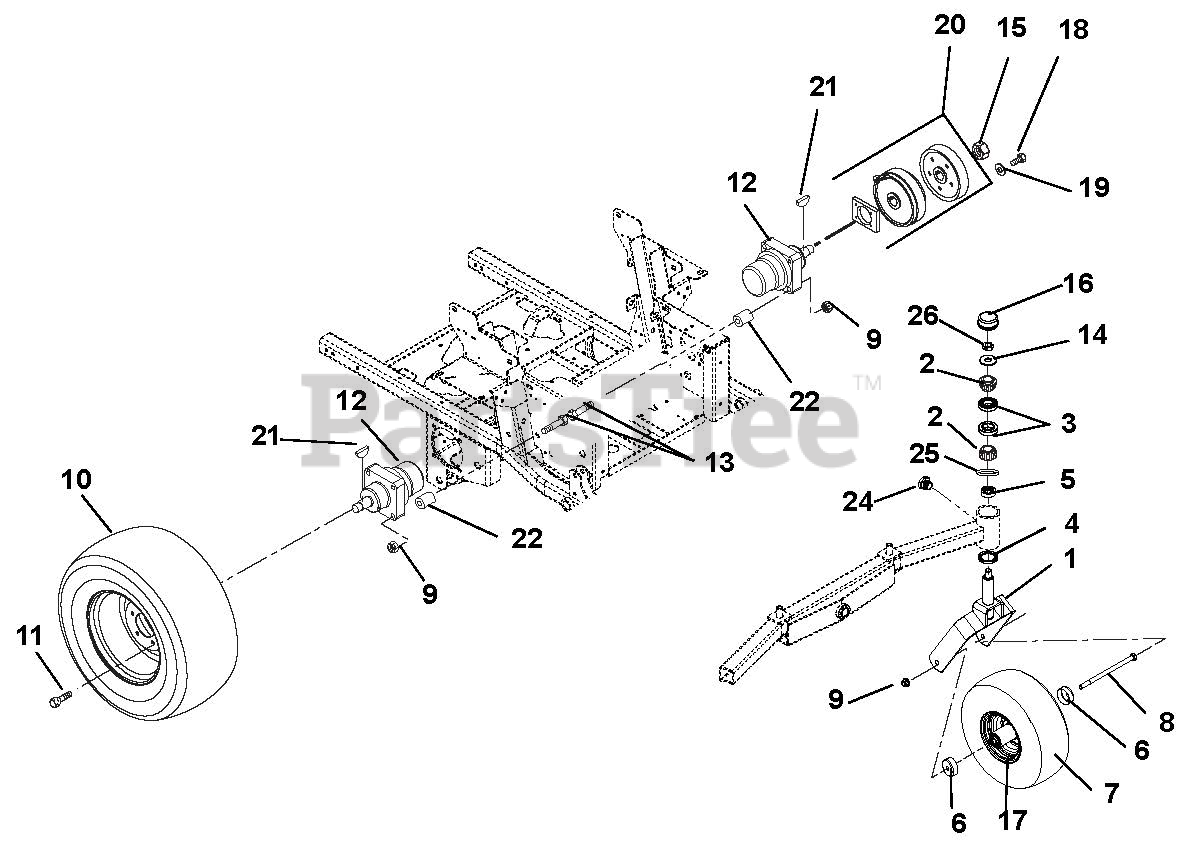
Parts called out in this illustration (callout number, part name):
1	Fork, Front
2	Bearing, Cone
3	Bearing, Cup 2.328 x .465
4	Bearing Seal 1.75 x 2.332 x .312
5	Spacer, Front Caster Fork
6	Shield, Wheel Bearing
7	Wheel/Tire Assembly, 15 x 6-6, Smooth
7	Tire, 15 x 6-6, Smooth
8	Bolt, Hex .50-13 x 9.00 Grade 5
9	Nut, Locking Top Flange .50-13
10	Tire/Wheel Assembly, 24 x 12.00-12
10	Tire, 24 x 11.50-12
11	Bolt, Lug .50-20 x 1.38
12	Wheel Motor, Parker
13	Bolt, Wheel Motor .50-13 x 5.00
14	Washer, Flat Steel .812 x 2.00 x .148
15	Nut, Top Lock Jam .75-16
16	Cap, Dust
17	Bearing, Cup 1.78 x .475
17	Bearing, Cone .750 x .61
18	Bolt, Hex .31-18 x 1.50 Grade 8 EP30
19	Waher, Lock .31 x .078
20	Kit, Parking Brake Service
21	Key, Woodruff .31 x 1.00
22	Bushing, .513 x .748 x 2.129
24	Plug, .250-28 x .185 Hex Head
26	Nut, Jam TOPLK .75-16
